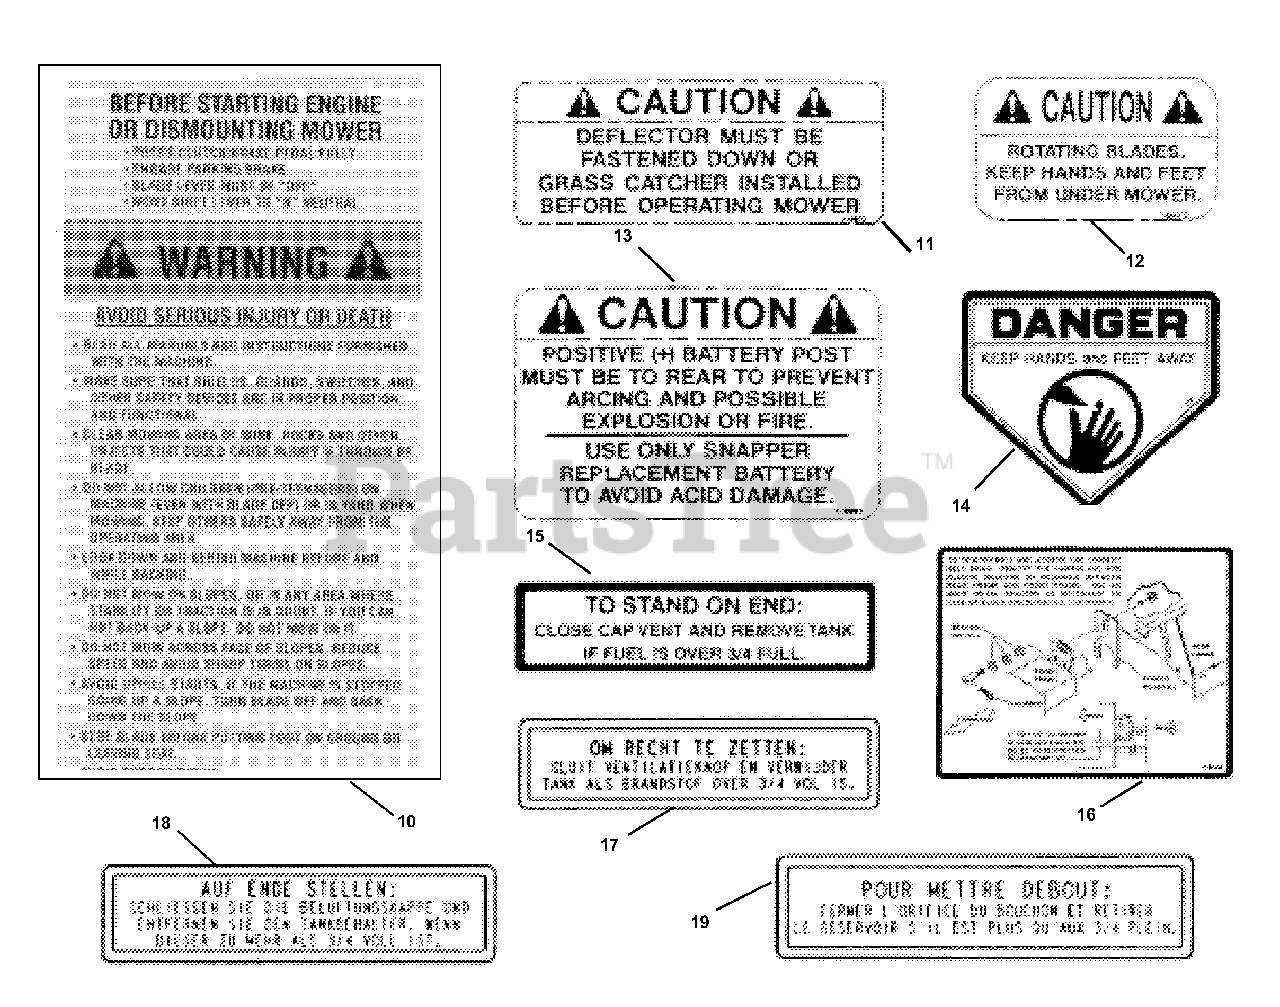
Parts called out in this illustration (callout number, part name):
10	DECAL, Safety Instruction Warning
11	DECAL, CAUTION, Deflector
12	DECAL, CAUTION, Rotating Blades
13	DECAL, CAUTION, Battery
14	DECAL, DANGER
15	DECAL, CAUTION, Fuel
16	DECAL, Belt Adjustment
17	DECAL, CAUTION, Fuel Leakage (Dutch)
18	DECAL, CAUTION, Fuel Leakage (German)
19	DECAL, CAUTION, Fuel Leakage (French)
